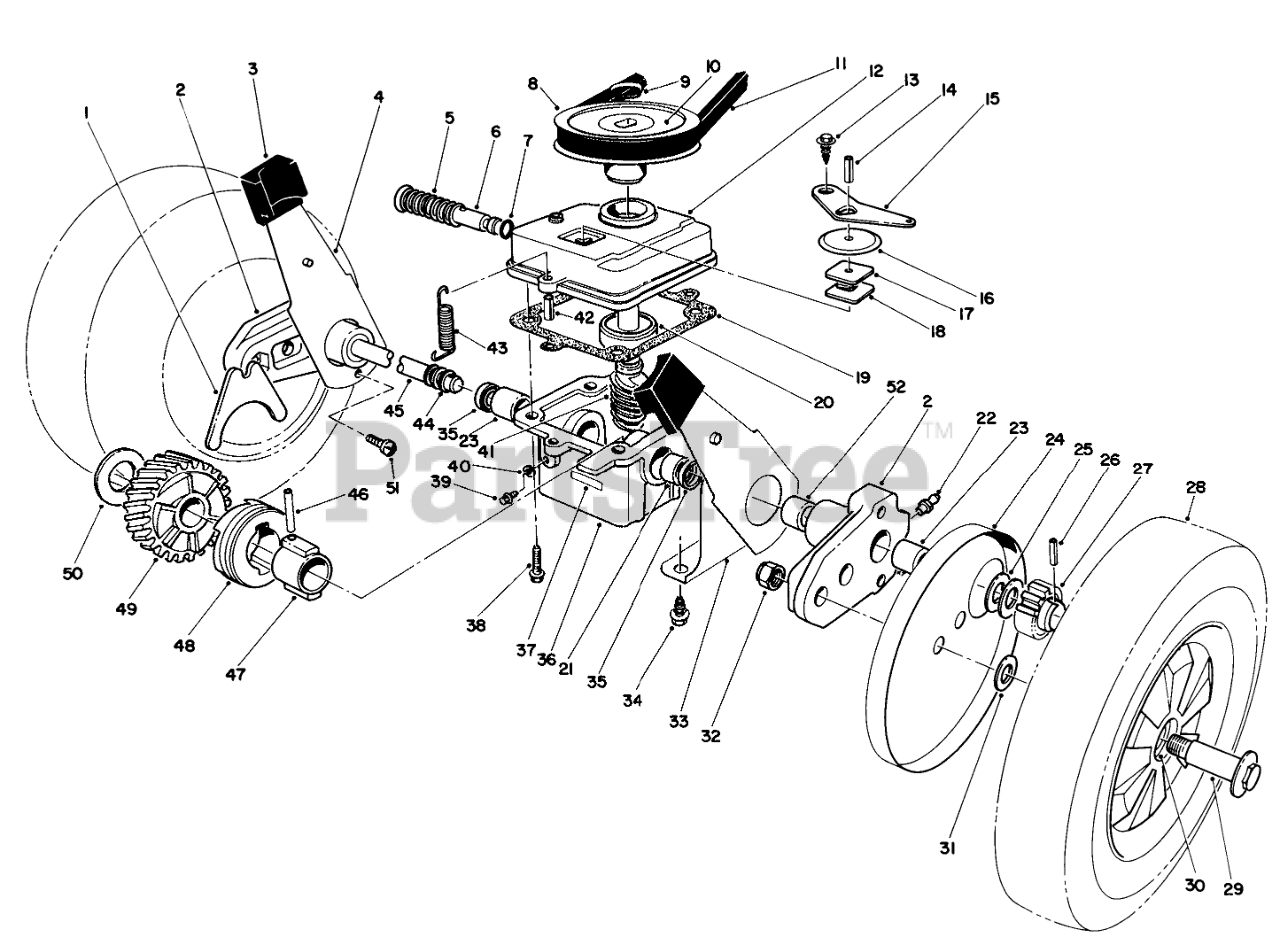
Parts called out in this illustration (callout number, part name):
1	SHIFTER FORK
2	Arm-Pivot (Incl. Ref. #22, 23 & 52)
3	KNOB-ARM
4	SPRING ARM ASSY-FRONT
5	SPRING
6	SHIFTER ROD
7	O-RING
8	PULLEY
9	PUSH-ON 93-3236
10	DECAL
11	V BELT
12	GEAR CASE COVER
13	Screw
14	SPIROL PIN H D
15	SHIFTER ARM
16	DUST COVER
17	DUST FILTER
18	LATCH PLATE
19	GASKET
20	BEARING
21	BUSHING
22	FITTING-GREASE
23	BUSHING
24	Cover-Wheel
25	THRUST WASHER
26	Pin
27	PINION GEAR 15T
28	Wheel, Tire, & Gear Assembly (Incl. Ref. #30)
29	BOLT-WHEEL
30	BUSHING
31	WASHER
32	Nut
33	END CAP
34	SCREW-HWHTF
35	SEAL-OIL
36	Gear Case (Incl. Ref. #21, 23, & 35)
37	DECAL
38	Screw
39	NYLON SCREW
40	FILL PLUG GASKET
41	Worm Shaft & Gear (Incl. Ref. #49)
42	3/16 X 1/2 ROLL PIN
43	TENSION SPRING
44	COVER-SHAFT, DRIVE
45	DRIVE SHAFT
46	COIL PIN
47	SLEEVE
48	CLUTCH JAW
49	Helical Gear
50	THRUST WASHER
51	SCREW
52	BUSHING
